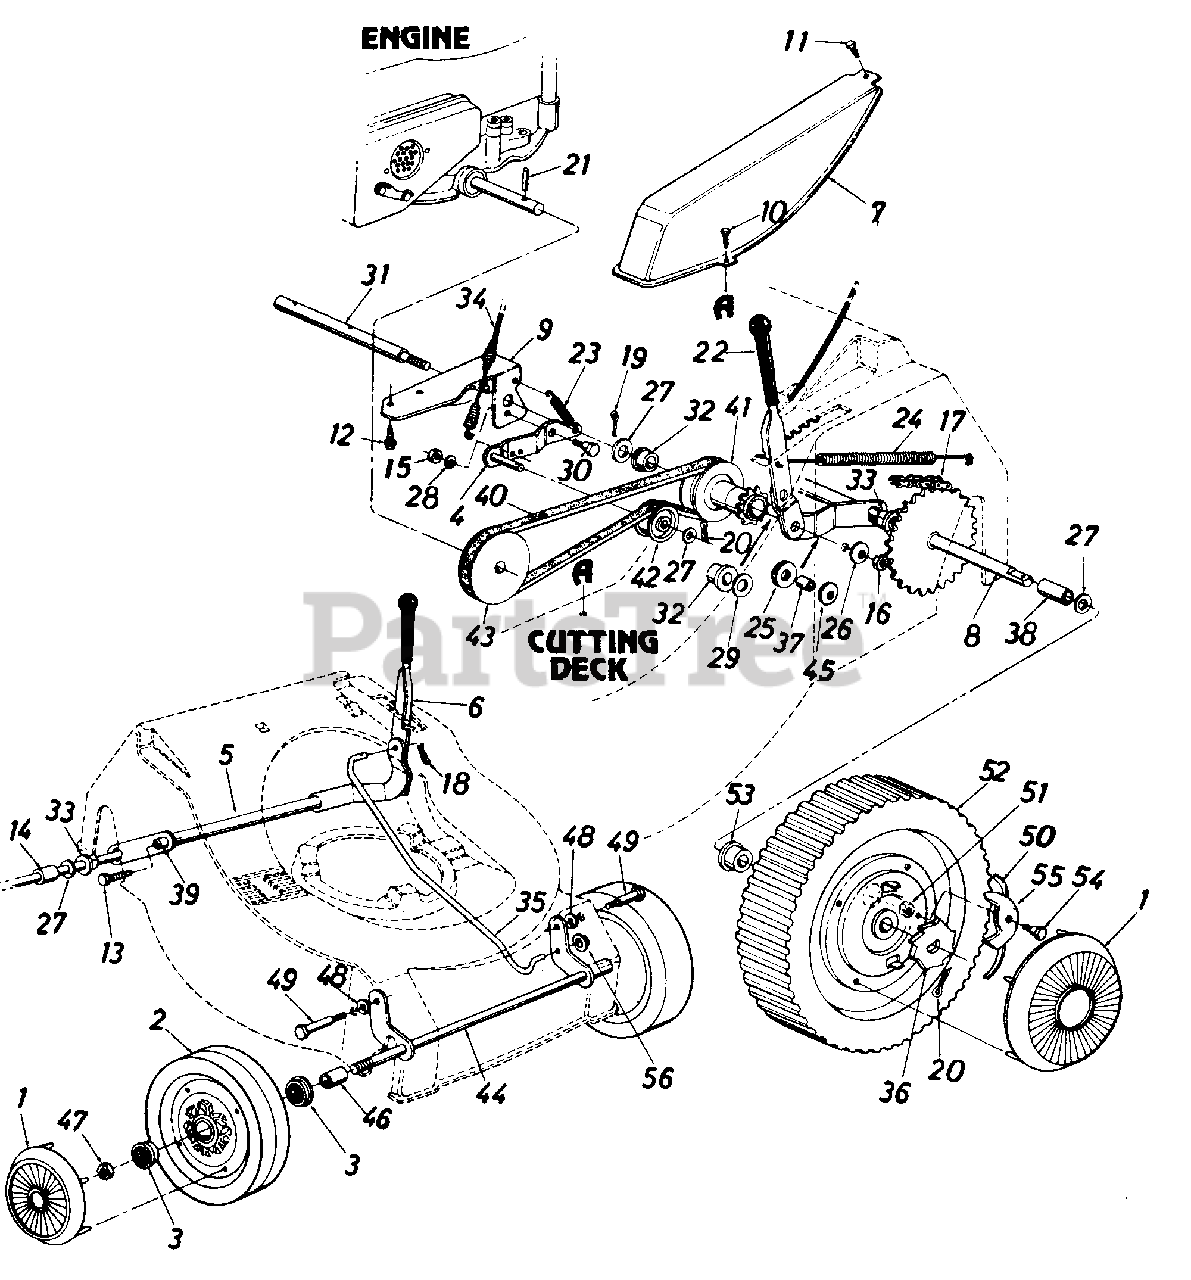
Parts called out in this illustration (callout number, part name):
1	Hub Cap
2	Wheel Ass'y. Comp. 8 x 1.75-Front
3	Flanged Ball Brg. .500" I.D.
4	Idler Brk't. Ass'y.
5	Axle Ass'y.
6	Height Adj. Handle
7	Belt Cover
8	Rear Shaft Ass'y.
9	Bracket-Pulley Shaft
10	Hex B-Tap Scr. 1/4 x .38" Lg.
11	IHex Drilling Scr. #10 x .50"
12	Hex Wash. Hd. B-Tap Scr. 5/16-18 x .50" Lg.
13	Hex Wash. Hd. TT-Tap Scr. 3/8-16 x 1.00" Lg.
14	Spacer .526" I.D. x .690" O.D. x .640" Lg.
15	Hex Nut 1/4-20 Thd.
16	Hex Jam Nut 3/8-16 Thd.
17	#48 Chain 1/2" Pitch x 34 Links-E.
18	Intern. Cot. Pin 5/16" Dia.
19	Cotter Pin 3/32" Dia. x 1.00" Lg.
20	Cot. Pin 1/8" Dia. x 1.00" Lg.
21	Spring Pin Spir. 3116" Dia. x 1.50" Lg.
22	Grip-Black
23	Extension Spring .33" O.D. x 1.12" Lg.
24	Extension Spring .50" O.D. x 4.25" Lg.
25	Rubber Wash.
26	Bell-Wash. .400" I.D. x .88" O.D.
27	Fl-Wash. .531" I.D. x .930" O.D.
28	L-Wash. 1/4" I.D.
29	Fl-Wash. .390" I.D. x 1.00" O.D.
30	Shld. Bolt.375" Dia. x .181
31	Pulley Shaft .500" Dia.
32	Flange Brg. .506" I.D. Plastic
33	Hex Flange Brg. x .506" I.D. Plastic
34	Drive Clutch Cable-50" Lg.
35	Linkage Rod .38" Dia.
36	Ratchet Wheel
37	Spacer .395" I.D. x .503" O.D. x .562" Lg.
38	Spacer .75" I.D. x .88" O.D. x 1.41 " Lg.
39	Spacer .385" I.D. x .503" O.D. x .270" Lg.
40	"V"-Belt 1/2" x 33" Lg.
41	Pulley w/9 Tooth Sprocket Ass'y.
42	Flat Idler Plastic 1.62" Dia.
43	"V"-Pulley .50" I.D. x 2.52" O.D.
44	Front Axle Ass'y.
45	Belleville Washer .40" I.D. x 1.13" O.D.
46	Sleeve .526" I.D. x .690" O.D. x .880 Lg.
47	Hex Ins. L-Nut 1/2-20 Thd.
48	Int. L-Wash. 3/8" I.D.
49	Shld. Bolt .625 Dia. x .425
50	Spring-Nylon
51	Hex Ins. L-Nut 1/4-20 Thd.
52	Wheel Ass'y. Comp. 9.25 x 1.75 Rear
53	Flanged Ball Brg. .500" I.D.
54	Shoulder Bolt .342" Dia. x .268
55	Pawl
56	Cap Speed Nut 5/16" Rod
